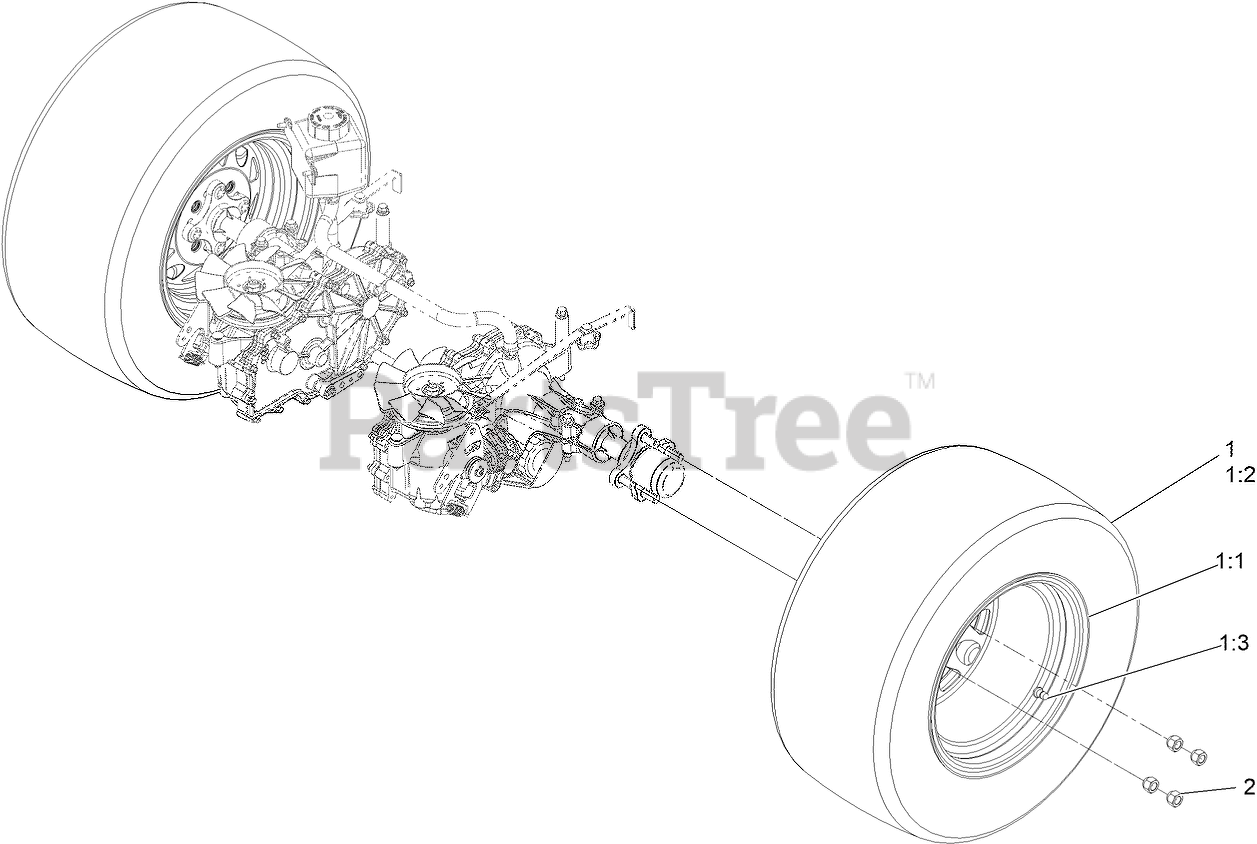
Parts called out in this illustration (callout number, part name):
1	WHEEL AND TIRE ASM
1:2	TIRE 23 X 10.50-12
1:3	VALVE
2	NUT-LUG
